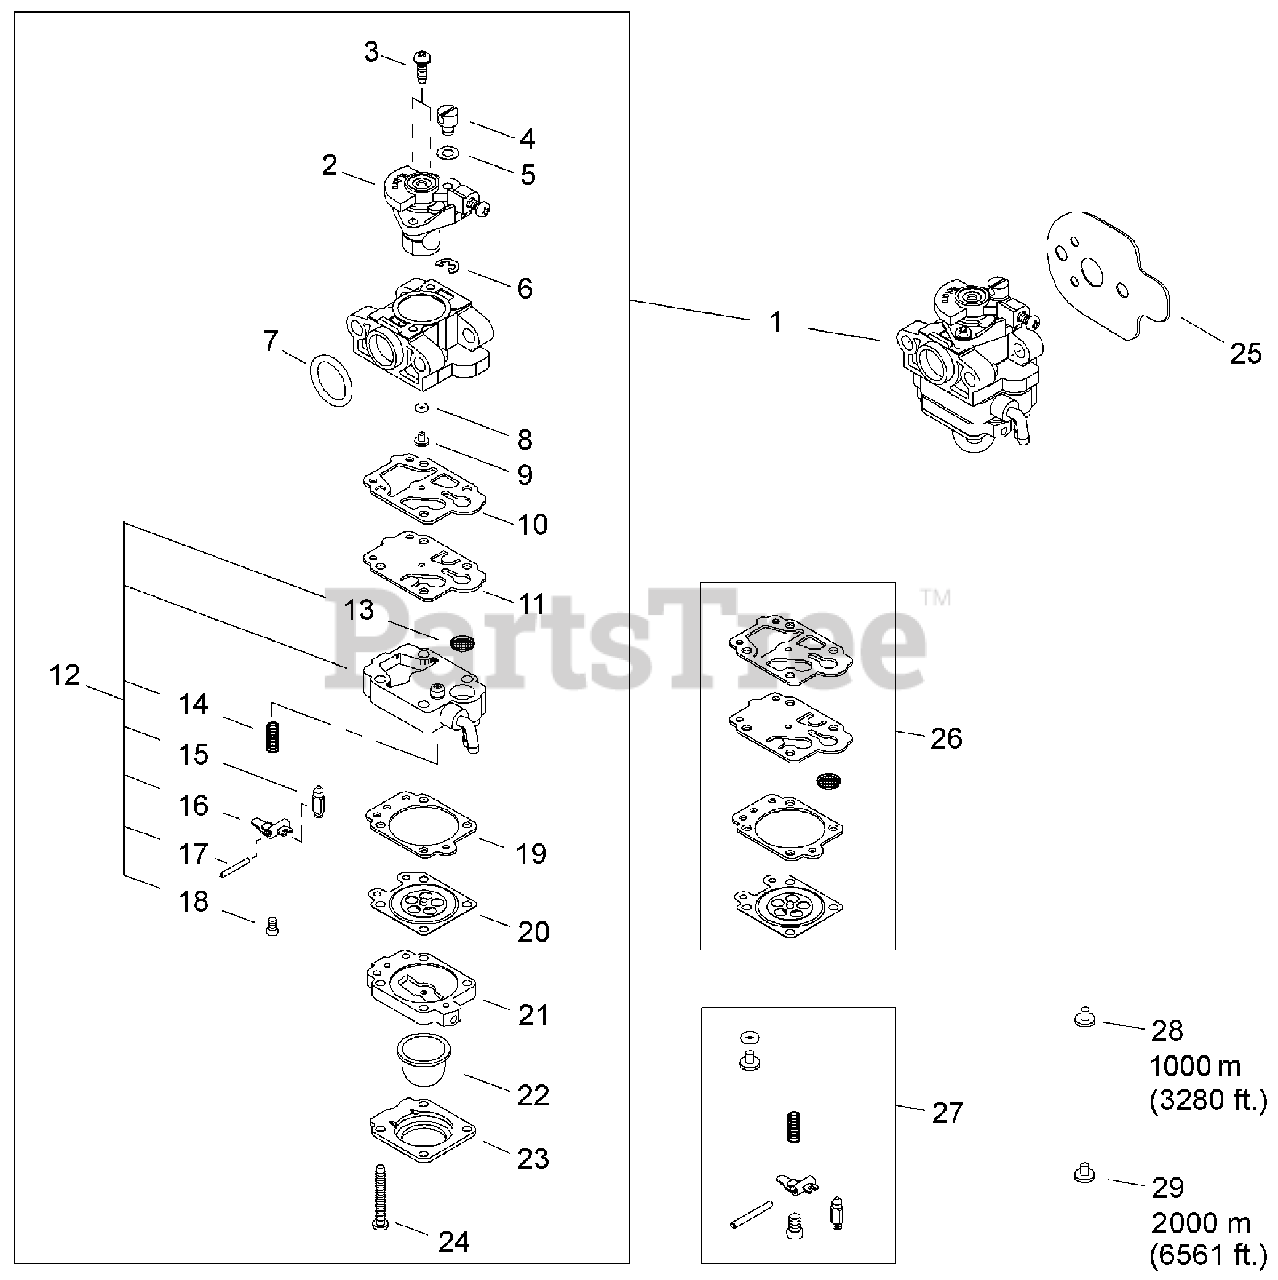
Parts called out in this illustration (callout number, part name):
1	CARBURETOR
2	VALVE ASSY, THROTTLE
3	SCREW, THROTTLE COLLAR
4	SWIVEL
5	WASHER
6	E-RING
7	O-RING 15
8	O-RING
9	JET, MAIN
10	GASKET, PUMP
11	DIAPHRAGM, PUMP
12	BODY ASSY, PUMP
13	SCREEN, FUEL INLET
14	SPRING, METERING LEVER
15	VALVE, INLET NEEDLE
16	LEVER, METERING
17	PIN, METERING LEVER
18	SCREW
19	GASKET, METERING DIAPHRAGM
20	DIAPHRAGM, METERING
21	BODY ASSY, PURGE
22	BULB, PURGE
23	RETAINER, PURGE BULB
24	SCREW
25	GASKET, INTAKE
26	GASKET / DIAPHRAGM KIT
27	VALVE KIT, INLET NEEDLE
28	JET, MAIN #40
29	JET, MAIN #39
